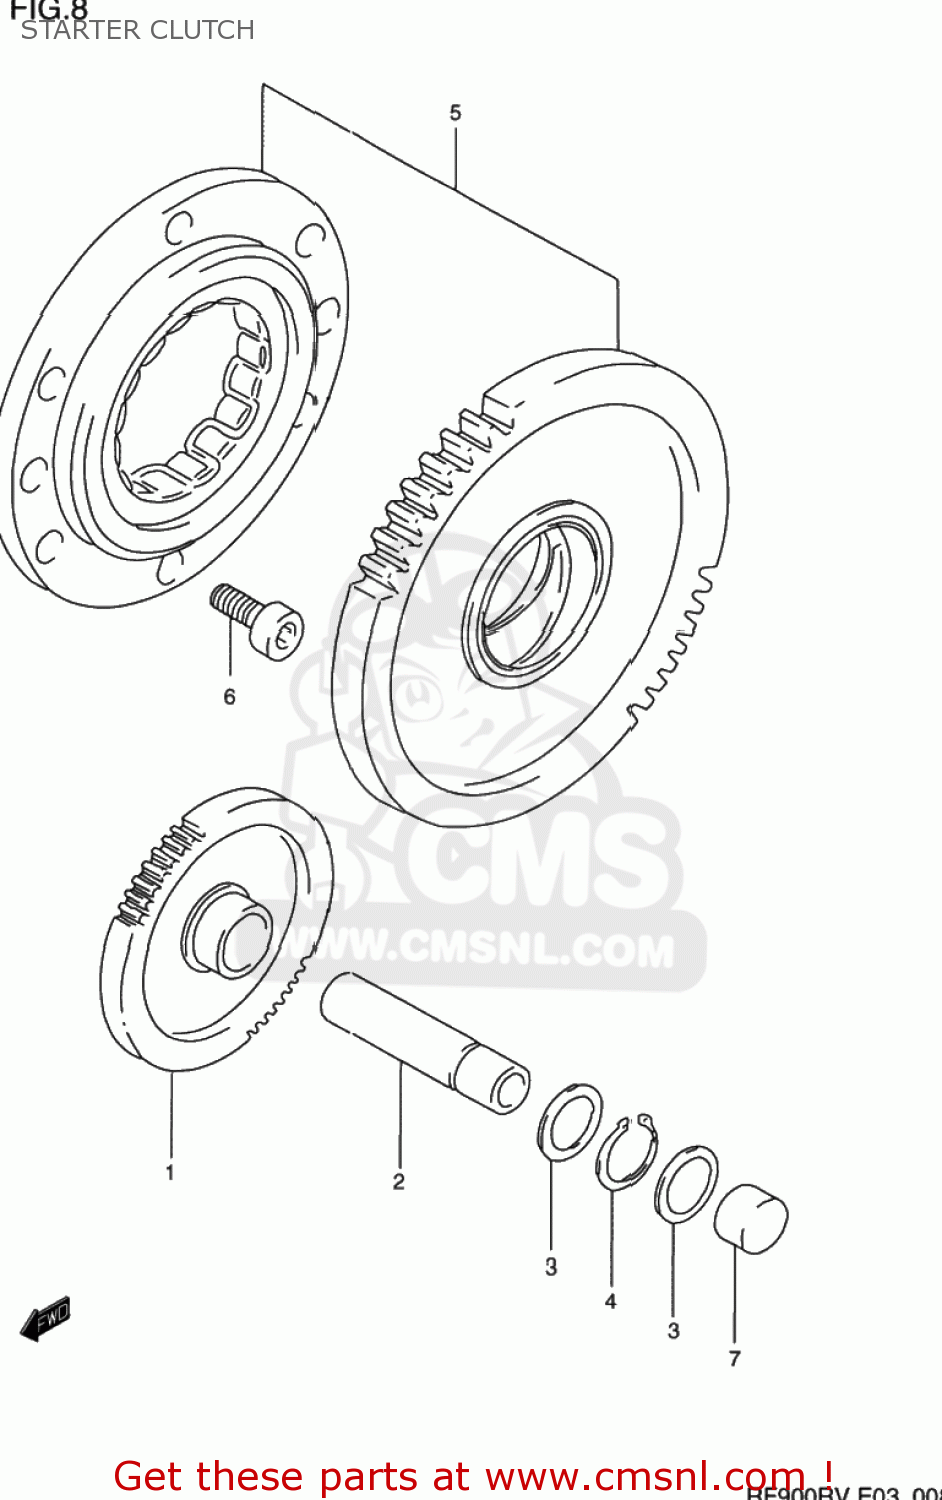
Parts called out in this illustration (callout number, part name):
1	GEAR,STARTER IDLE (NT:1
2	SHAFT,STARTER IDLE GEAR
3	WASHER
4	CIRCLIP,12 MM
5	CLUTCH SET,STARTER
6	BOLT,STRANGER
7	PLUG
